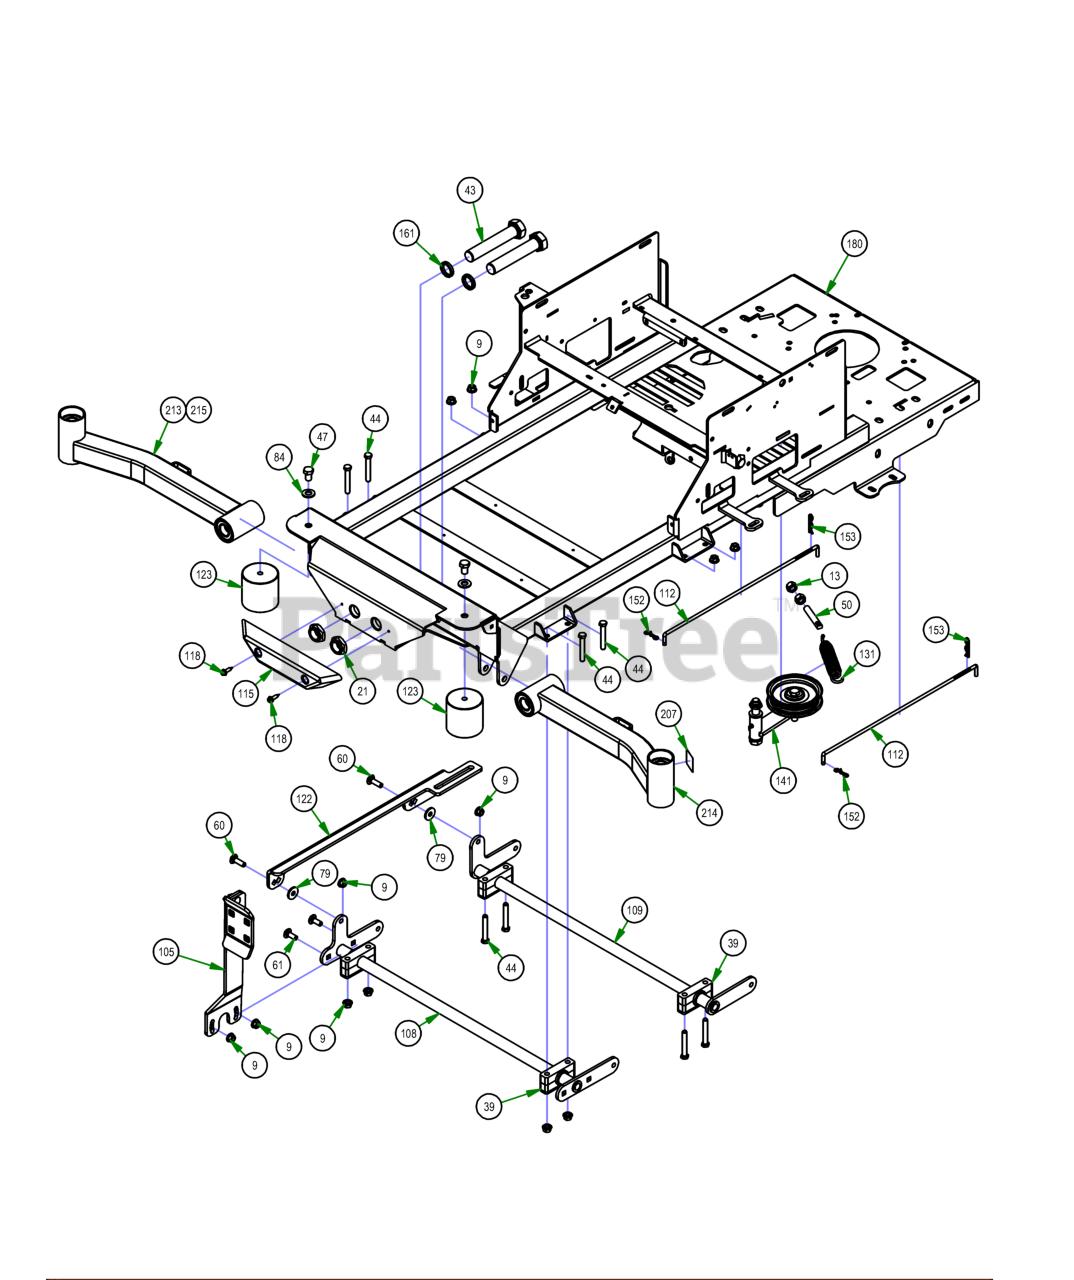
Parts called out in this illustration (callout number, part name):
9	3/8-16 NYLON INSERT FLANGE LOCKNUT (GR.F) ZINC
13	1/2-13 HEX NUT ZINC
21	1"-14 NYLON INSERT JAM LOCKNUT ZINC
39	Pillow Block Kit
43	1"-14 X 5-1/2 HEX CAP SCREW (GR.8) ZINC YELLOW
44	3/8-16 X 2-1/2 HEX CAP SCREW (GR.5) ZINC
47	1/2-13 X 3/4 HEX CAP SCREW (GR.5) ZINC
50	All Thread
60	3/8-16 X 1-1/4 CARRIAGE BOLT ZINC
61	3/8-16 X 1 CARRIAGE BOLT (GR.5) ZINC
79	.390 ID X 1.12 OD X .125 THK FLAT WASHER NYLON
84	1/2 SAE FLAT WASHER (1-1/16" OD) GR.8 ZINC YELLOW
105	Foot Pedal Assembly
108	Actuator Bar Front- 2017 MZ/ZT
109	Actuator Bar Rear- 2017 MZ/ZT
112	Neutral Rod
115	Bumper EZT
118	1/4 x 1 Hex Head Tek Screw
119	5/16-18 X 3/4 HEX WASHER SLOT (F) TCS ZINC
122	2017 MZ/ZT Actuator Linkage
123	Vibration Mount- Red Dot
131	Deck Idler Spring
141	ZT Pump Idler
153	Neutral Rod Clip
161	Spacer, 1x1.375x.25
180	2021 ZT Frame - Painted
207	Independetly Articulating Front Suspension Arms Patent Decal
213	2021 ZT Suspension Arm Assembly Short Right (48")
214	2021 ZT Suspension Arm Assembly Left (48", 54", & 60")
215	2021 ZT Suspension Arm Assembly Long Right (54" & 60")
